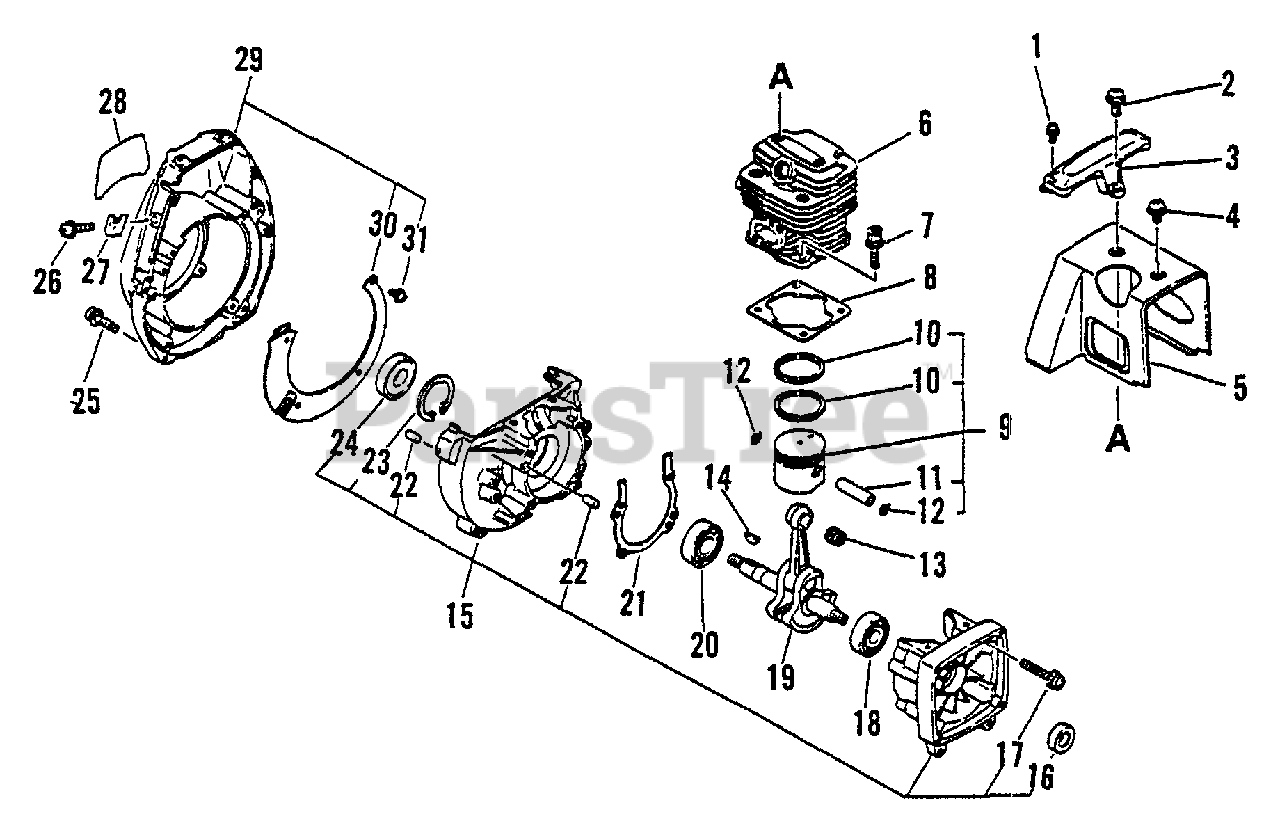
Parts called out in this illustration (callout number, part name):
1	SCREW - 4X14
2	SCREW - 5X16
3	GUARD - TOP
4	SCREW - 5X10
5	COVER, ENGINE
6	CYLINDER
7	SCREW - 5X20
8	GASKET, CYLINDER
9	PISTON KIT
10	RING, PISTON
11	PIN, PISTON
12	RING, RETAINING
13	BEARING, NEEDLE
15	CRANKCASE KIT
16	SEAL, OIL
17	SCREW - 5X30
18	BEARING, BALL - 6201
19	CRANKSHAFT ASSY
20	BEARING, BALL - 6202
21	GASKET, CRANKCASE
22	PIN - LOCATING
23	RING, RETAINING - 35
24	SEAL, OIL
25	SCREW - 5X25
26	SCREW - 4X10
27	HOLDER, CABLE
29	FAN CASE ASSY
30	SHIELD, FAN
31	SCREW - 4X8
